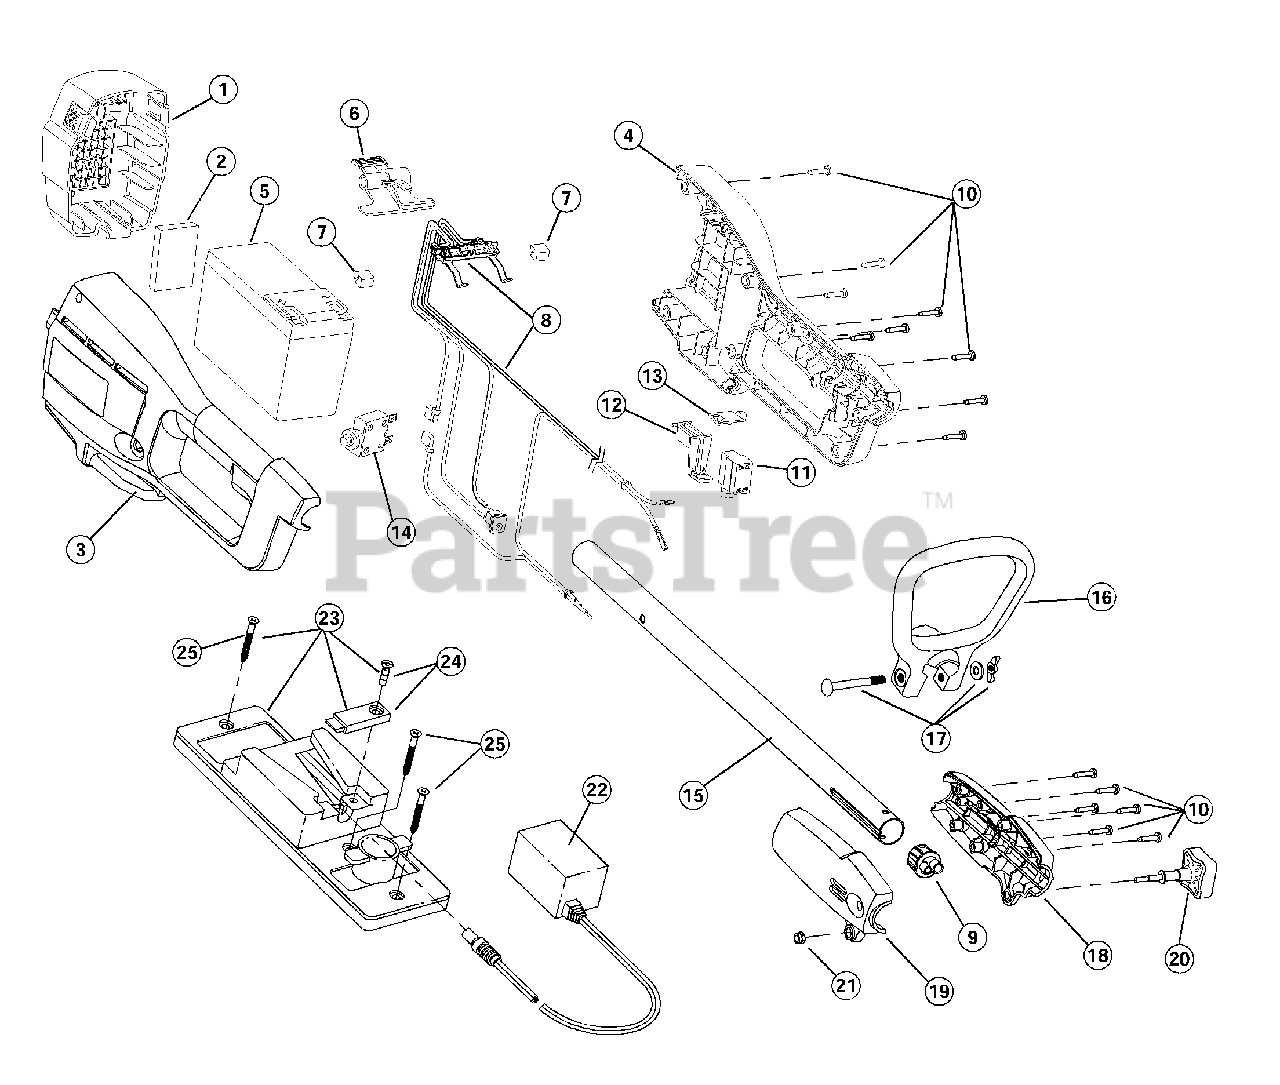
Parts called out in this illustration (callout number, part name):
1	Battery Door
2	Foam Pad
3	Right Battery Housing
4	Left Battery Housing
5	12 Volt Battery
6	Battery Latch
7	Terminal Spacer
8	Wiring Harness Assembly
9	Plug Connector
10	Housing Screw
11	Switch Assembly
12	Trigger
13	Lock-Off Button
14	Circuit Breaker
15	Upper Motor Wire Tube
16	D-Handle
17	Handle Hardware
18	Left Coupler Housing
19	Right Coupler Housing
20	Knob
21	Lock Nut
22	12 Volt Charger
23	Charging Station Stand
24	Barrel Clamp with Screw
25	Mounting Screw
